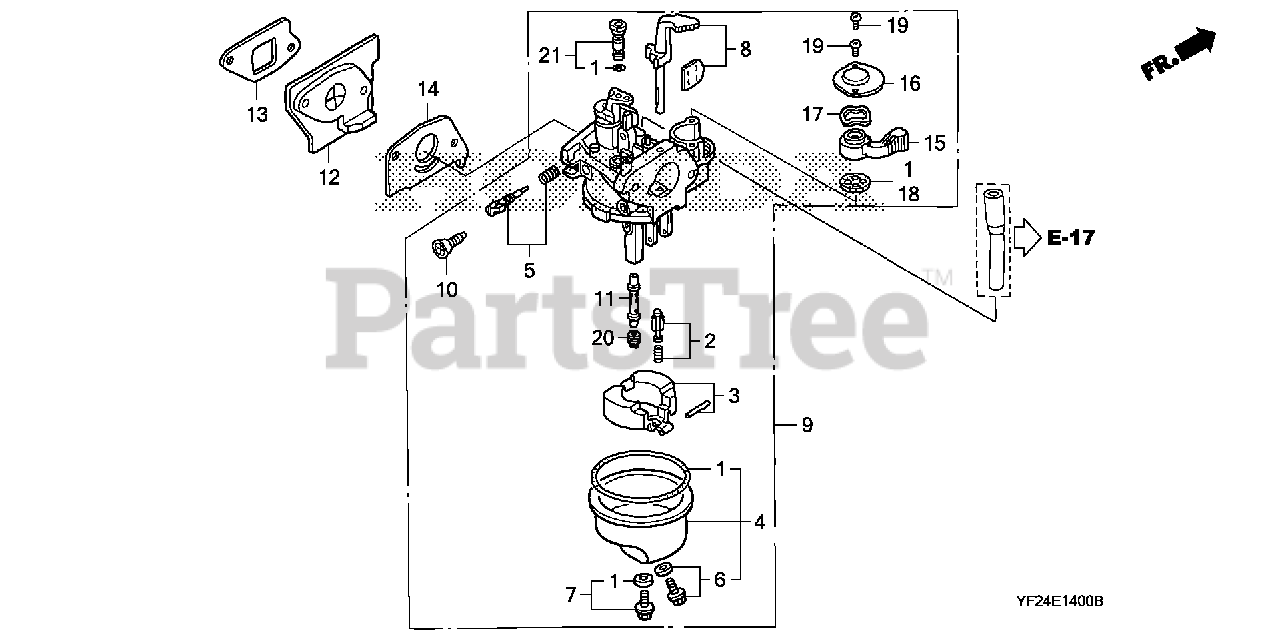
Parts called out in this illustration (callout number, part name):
1	GASKET SET
2	VALVE SET, FLOAT (SEAT NOT INCLUDED)
4	CHAMBER SET, FLOAT
5	SCREW SET, PILOT (CARBURETOR NO.)
6	SCREW SET, DRAIN
7	SCREW SET
8	CHOKE SET (CARBURETOR NO.)
9	CARBURETOR ASSY. (BF32E B)
9	CARBURETOR ASSY. (BF32E C)
9	CARBURETOR ASSY. (BF32E D)
9	CARBURETOR ASSY. (BF32E G)
10	SCREW, THROTTLE STOP
11	NOZZLE, MAIN (CARBURETOR NO.)
12	INSULATOR, CARBURETOR
13	GASKET, INSULATOR
14	GASKET, CARBURETOR
15	LEVER, PETCOCK
16	PLATE, LEVER SETTING
17	SPRING, PETCOCK LEVER
18	GASKET, PETCOCK
19	SCREW, PAN (3X6)
20	JET, MAIN (#50)
20	JET, MAIN (#52) (CARBURETOR NO.)
20	JET, MAIN (#55) (CARBURETOR NO.)
21	JET SET, PILOT (#35)
